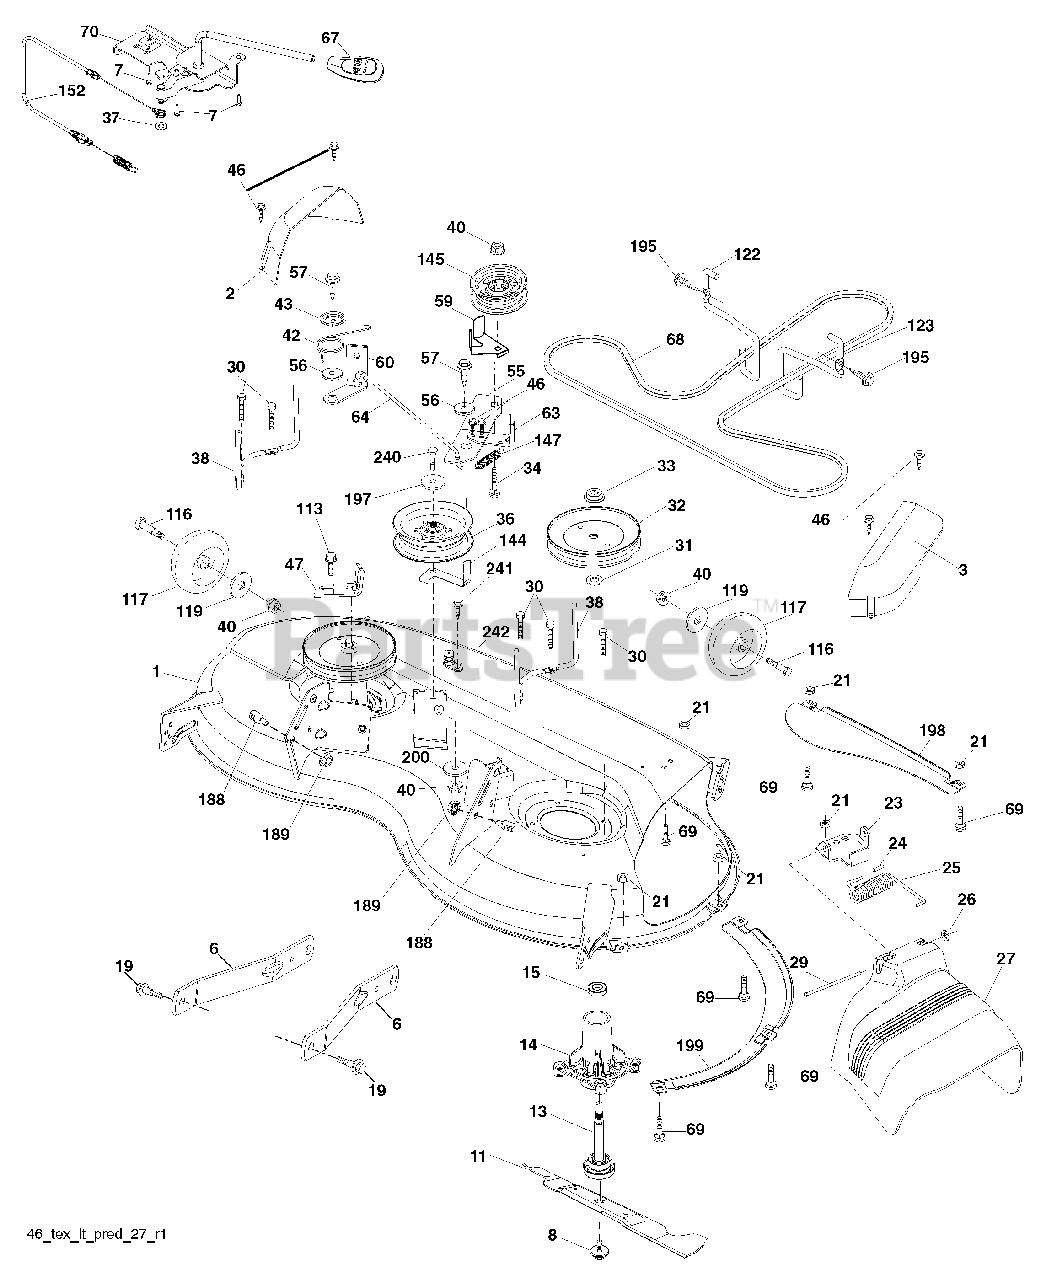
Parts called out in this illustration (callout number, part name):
1	Mower Housing
2	Cover Mandrel RH
3	Cover Mandrel LH
6	Arm Suspension
7	Screw #10 x 0.750 BOS Thread
8	Bolt/Washer asm 7/16-20 unf
11	Blade Mower
13	Shaft Assembly, Mandrel
14	Housing, Mandrel
15	Bearing, Ball, Mandrel
19	Bolt, Shoulder
21	Nut
23	Bracket, Deflector
24	Cap, Sleeve
25	Spring, Torsion, Deflector
27	Shield, Deflector
29	Rod, Hinge
30	Screw Thdrol Rolling Wsh Hd
31	Washer, Spacer
32	Pulley, Mandrel
33	Nut, Toplock, Flanged
34	Bolt Carr Sh. 3/8-16 x 1-1/2 Gr. 5
36	Pulley, Idler, 4.50 RAW
37	Washer 13/32 x 13/16 x 16 Ga.
38	Keeper Belt LH Mandrel
40	Nut, Lock Flg. 3/8-16 unc
42	Spring Trosion Brake
43	Spring Torsion Retainer
47	Bracket Clutch Cable
55	Arm, Idler
56	Spacer, Retainer
57	Screw Hexwsh Thd 3/8-16 x 1
59	Guard, Tuv Idler (94)
60	Arm Brake Mower LH
63	Arm Brake Mower
64	Linkage Brake
67	Handle, Clutch Cable
68	V-Belt
69	Bolt
70	Clutch Asm. Cable
113	Screw 5/16-18
116	Bolt, Shoulder
117	Wheel, Gauge
119	Washer 13/32 x 1-1/4 x 12 Ga.
122	Keeper Belt Eng. LH
123	Keeper Belt Eng. RH
144	Keeper Belt
145	Pulley Idler
147	Spring Return
152	Cable Clutch Manual w/Spr.
188	Stud Fastener
189	Nut Lock Hex Flange
195	Screw 3/8-16 x 3/4
197	Washer 13/32 x 13/16 x 12 Ga.
198	Baffle Center Front
199	Baffle Front RH
200	Washer 13/32 x 1 x 1/2 Ga.
240	Bolt 3/8-16 unc x 2-1/4 Gr. 5
241	Screw TT #10-32.5 3/8 Flg.
242	Port Washout
